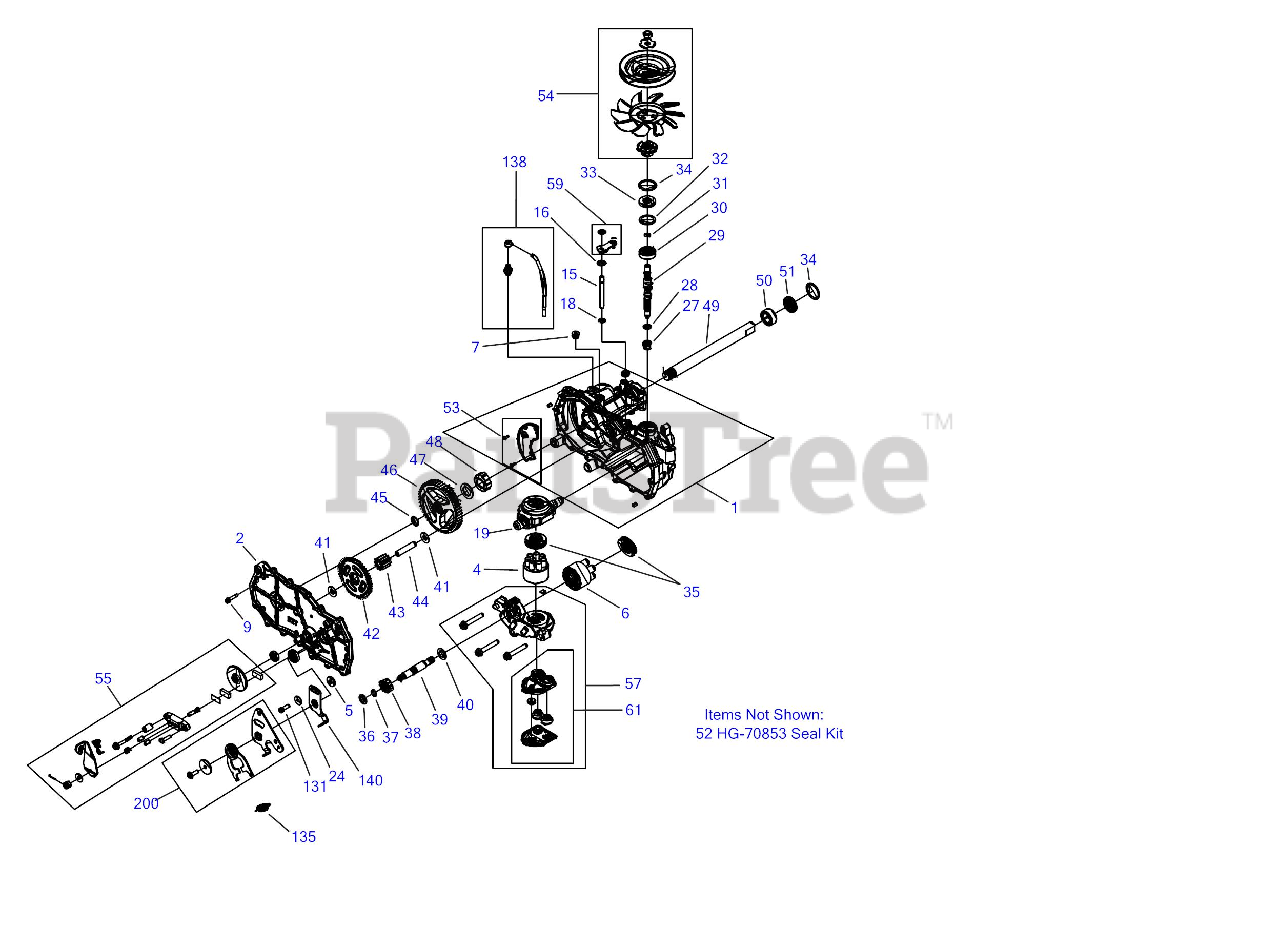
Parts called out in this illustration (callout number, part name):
1	Kit, Housing, Main, LH
2	Kit, Housing, Side, LH
4	Kit, Block, 7 Piston
5	Spacer, .320 x 1.005 x .150
6	Kit, Block, 10cc Cylinder
9	Screw, Hex Washer
15	Rod, Bypass
16	Ring, Ret .375 External
18	Ring, Retaining .375 External
19	Trunnion, Swashplate
24	Washer, .34 x .88 x .06
27	Spring, Block
28	Washer, .59 x .79 x .04
29	Shaft, Input
30	Ball Bearing 17 x 40 x 12
31	Ring, Reatining
32	Washer, 1.23 x 1.57 x .04
33	Seal, Lip 17 x 40 x 7
34	Ring Retaining Internal
35	Thrust Bearing, 30 x 52 x 13
36	Washer, .63 x 1.00 x .05
37	Ring, Reatining, Motor Shaft
38	Gear, 13T Pinion
39	Shaft, Motor
40	Washer, .71 x 1.16 x .04
42	Gear, 10T/48T
43	Gear, 10T Jackshaft
44	Pin, Jackshaft
45	Ring, Spiral Retaining-87
46	Gear, Bull 52T
47	Washer, 1.018 x 1.571 x .105
48	Buahing, Sleeve (Inboard)
49	Shaft, Axle, 1.00 x 11.70 DD
50	Bushing, 1.003 x 1.571 x .625
51	Seal, Lip, TC4, 1.00 x 1.577 x .27
52	Kit, Seals & Rings
53	Kit, Expansion Plate LH
54	Kit, Fan & Pulley
54	FAN-7.0 (10 BLADE)
54	HUB-PULLEY
54	WASHER-SLOTTED
55	Kit, Brake Arm
57	Kit, Center Section LH
59	Kit, Bypass Arm
61	Kit, Filter
131	Socket Cap Screw, 5/16-24 x 7/8
135	Spring, Extension
138	Kit, Breather
140	Arm, Left Return
200	Kit, RTN Bidirectional
